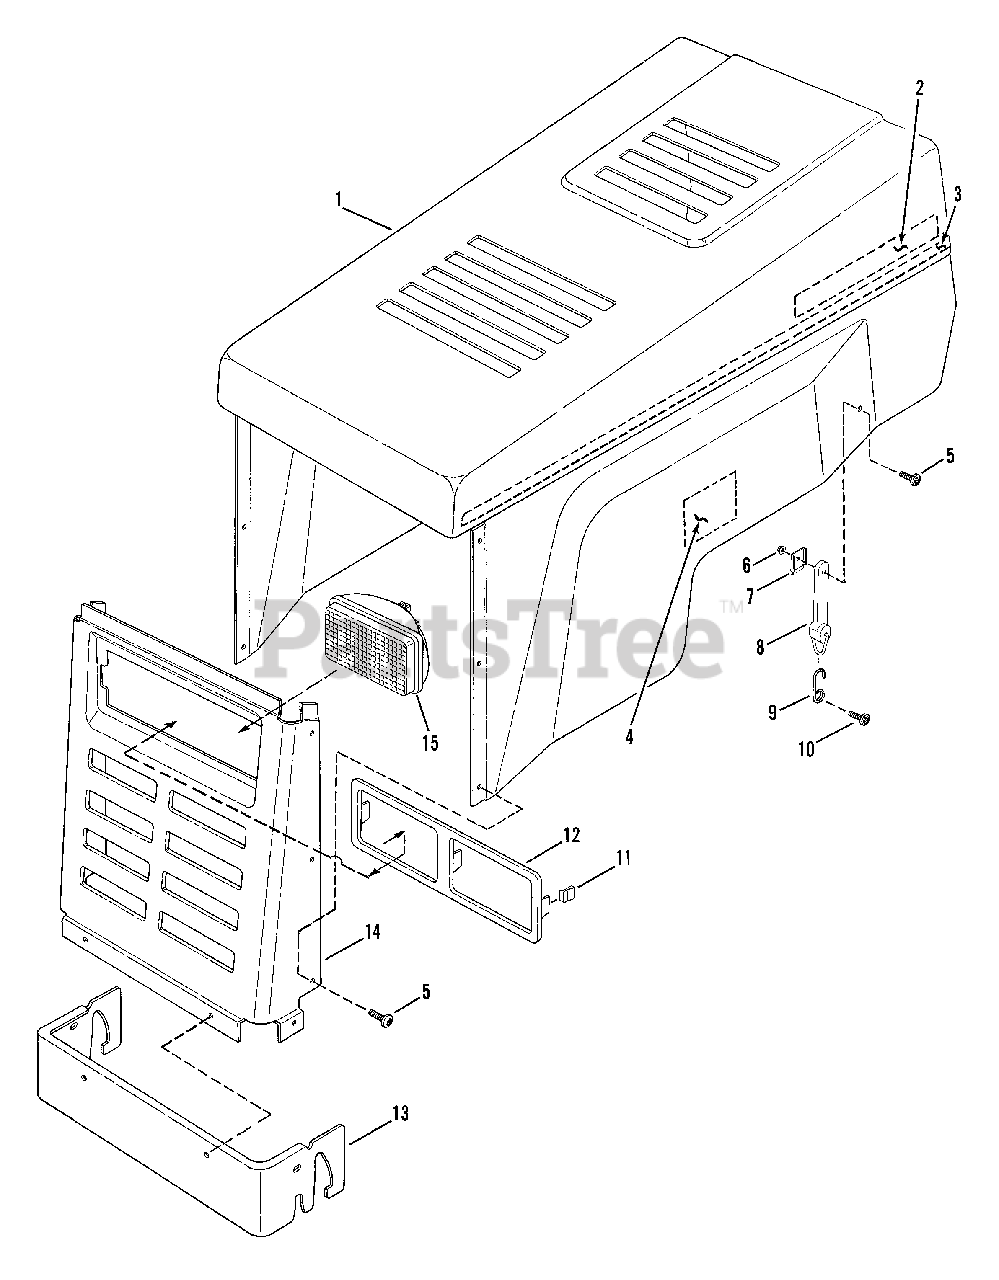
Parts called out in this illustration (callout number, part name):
1	HOOD, LTD 12
2	DECAL, SNAPPER
3	DECAL, Stripe
4	DECAL, LT12D, 6 SPEED, 33 HI-VAC
5	SCREW, 1/4-20x5/8" Torx Hd., S.T.
6	LOCKNUT, 1/4-20 Hex Flange
7	CLIP, Hood Latch
8	LATCH, Hood
9	ANCHOR, Hood Latch
10	SCREW, 5/16-18x7/8" Torx Hd., S.T.
11	CLIP, Head Lamp
12	BRACKET, Head Lamp
13	BUMPER
15	HEAD LAMP
